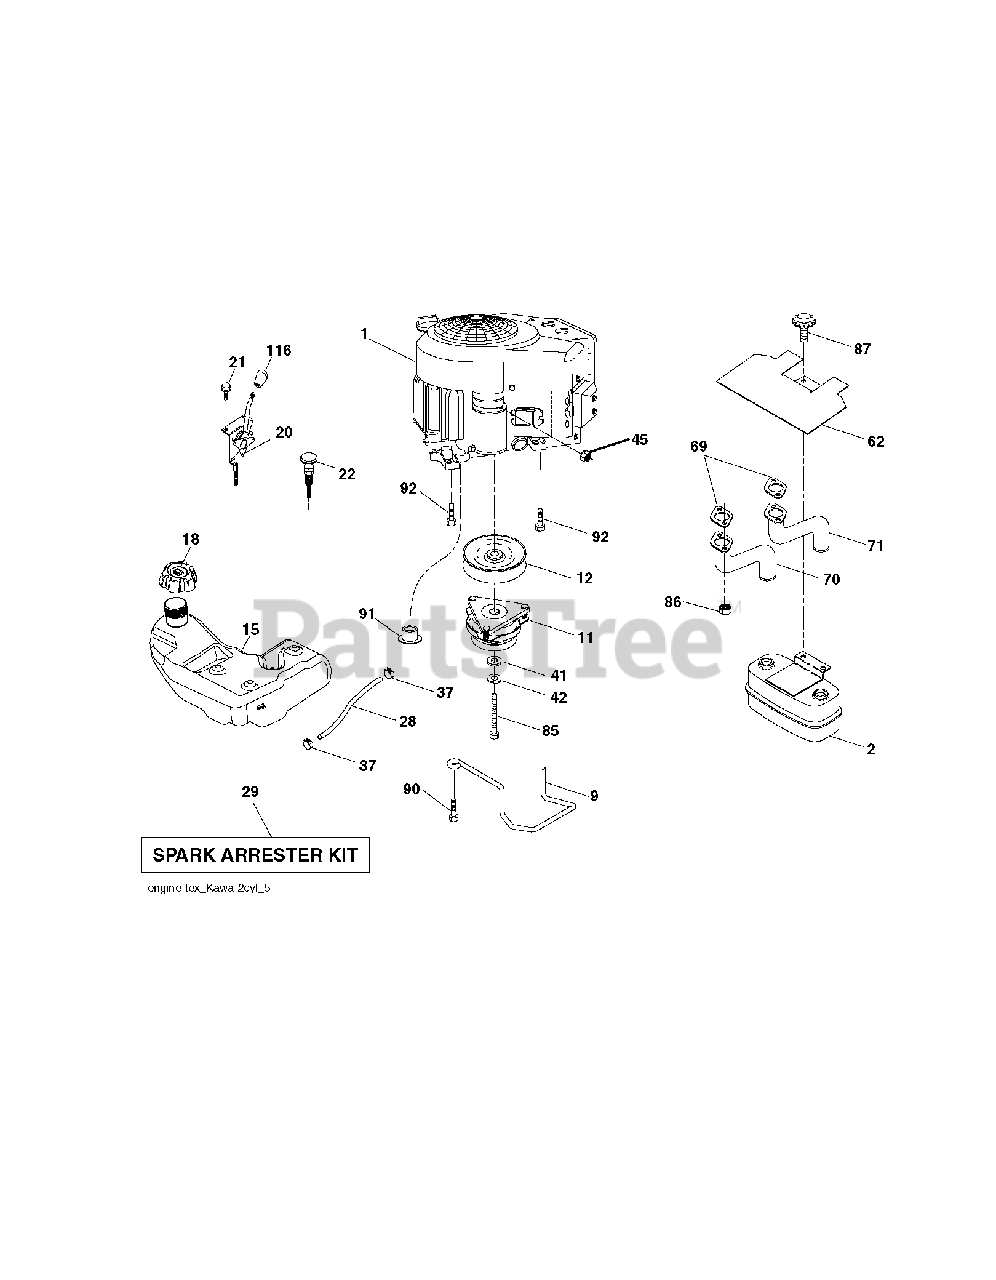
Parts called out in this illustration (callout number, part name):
2	MUFFLER.TWIN.CYL.LOW.TONE
9	KEEPER.BELT.ENGINE.4.2
11	CLUTCH ELECTRIC
12	PULLEY ENGINE
15	TANK.FUEL.4GAL
18	CAP.ASM.FUEL.TANK.3"BLACK
20	CONTROL.THROTTLE.PRO.
21	SCREW.#10 X 0.750.BOS (2 2)
22	CONTROL CHOKE
28	LINE.FUEL.64"REAR.EMIS
29	KIT.SPARK ARRESTOR(392390 B&S)
37	HOSE CLAMP
42	LOCKWASHER
45	NUT
62	SHIELD.HEAT.MUFFLER
70	RP.TUBE.EXHAUST.LH.FR961/FR730
71	RP.TUBE.EXHAUST.RH.FR961/FR730
85	BOLT HEX 7/16-20 X 3.75 GR. 5
86	NUT.HEX.FLANGE.TOPLOCK
87	BOLT.5/16-18UNCX1.W/SEMS.BLK
90	SCREW 3/8-16X1
91	BUSHING.1.375OD
92	SCREW 3/8-16X1
116	RP KNOB SOFT TOUCH
